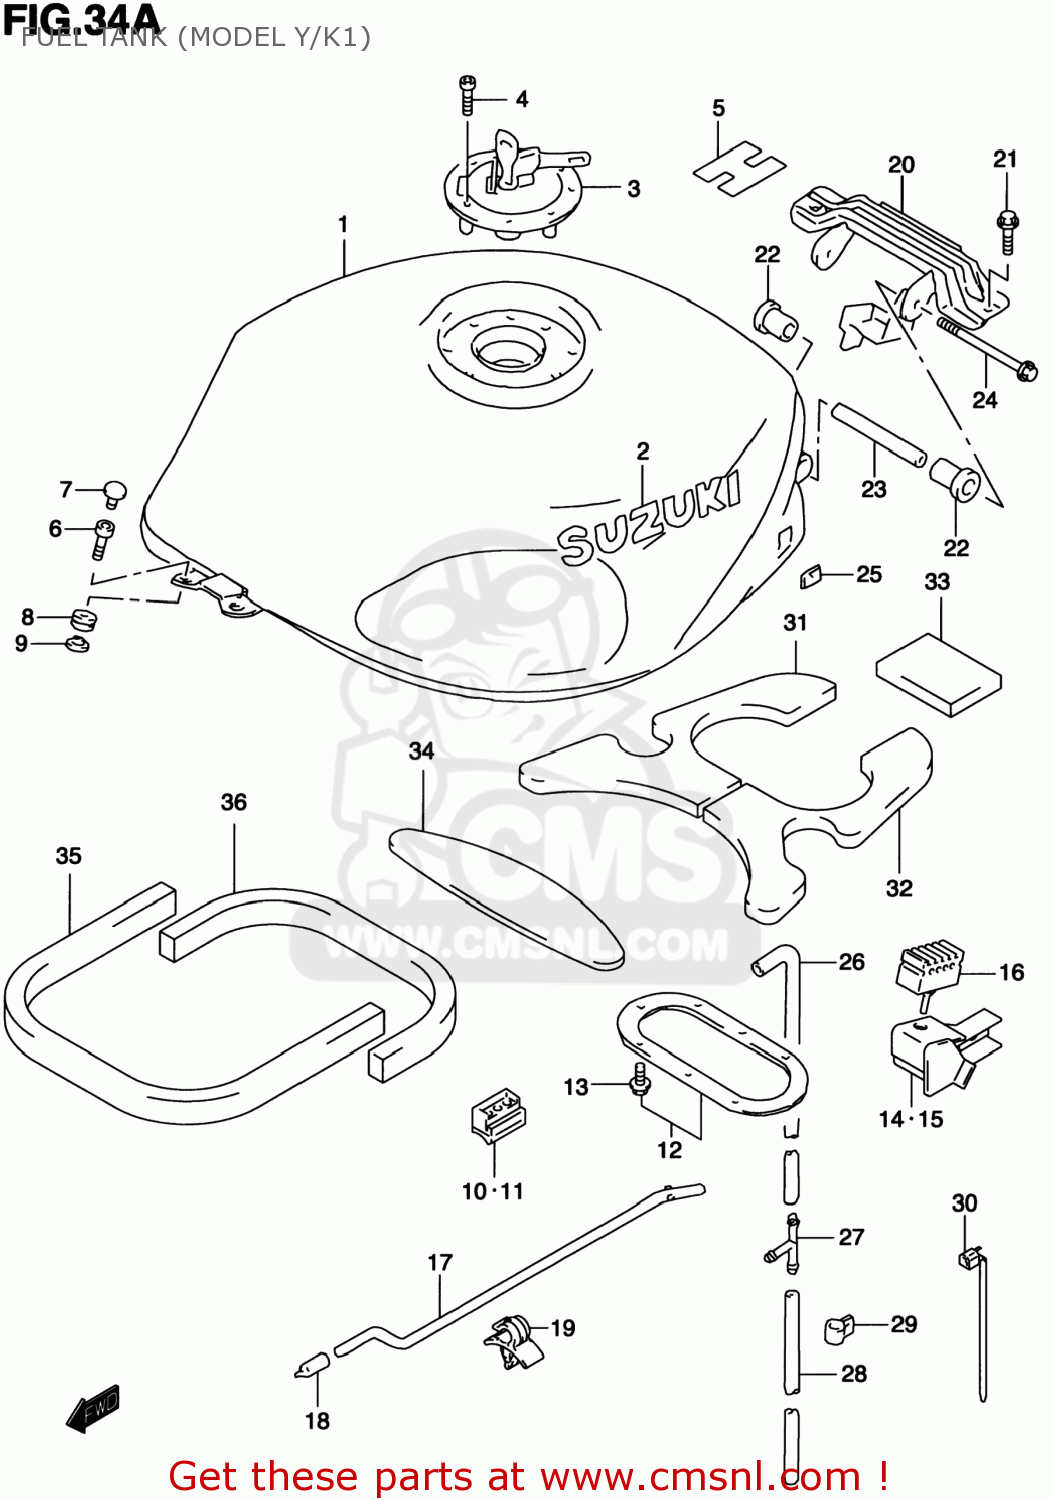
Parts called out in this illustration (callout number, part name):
1	TANK ASSEMBLY,FUEL
2	EMBLEM,FUEL TANK
3	CAP SET,FUEL TANK
4	BOLT(5X20)
5	LABEL,FUEL TANK INNER
6	BOLT
7	CAP,BOLT
8	CUSHION
9	WASHER
10	CUSHION,TANK SIDE,R
11	CUSHION,TANK SIDE,L
12	PACKING SET,FUEL PUMP (NAS)
13	BOLT,FUEL PUMP
14	BRACKET,FUEL TANK RR,R
15	BRACKET,FUEL TANK RR,L
16	CUSHION,TANK RR SIDE
17	STAY,FUEL TANK
18	CAP,OD:11
19	CLAMP
20	BRACKET,FUEL TANK RR
21	BOLT(8X16)
22	CUSHION,FUEL TANK RR
23	SPACER,FUEL TANK RR
24	BOLT
25	FASTENER,FUEL TANK
26	HOSE,FUEL TANK DRAIN
27	3 WAY
28	HOSE(7X10.2X600)
29	CLAMP
30	CLAMP(L:125)
31	SHIELD,FUEL TANK HEAT,R
32	SHIELD,FUEL TANK HEAT,L
33	SHIELD,FUEL TANK HEAT RR
34	SHIELD,FUEL TANK HEAT FR
35	SHIELD,FUEL TANK HEAT NO.1
36	SHIELD,FUEL TANK HEAT NO.2
